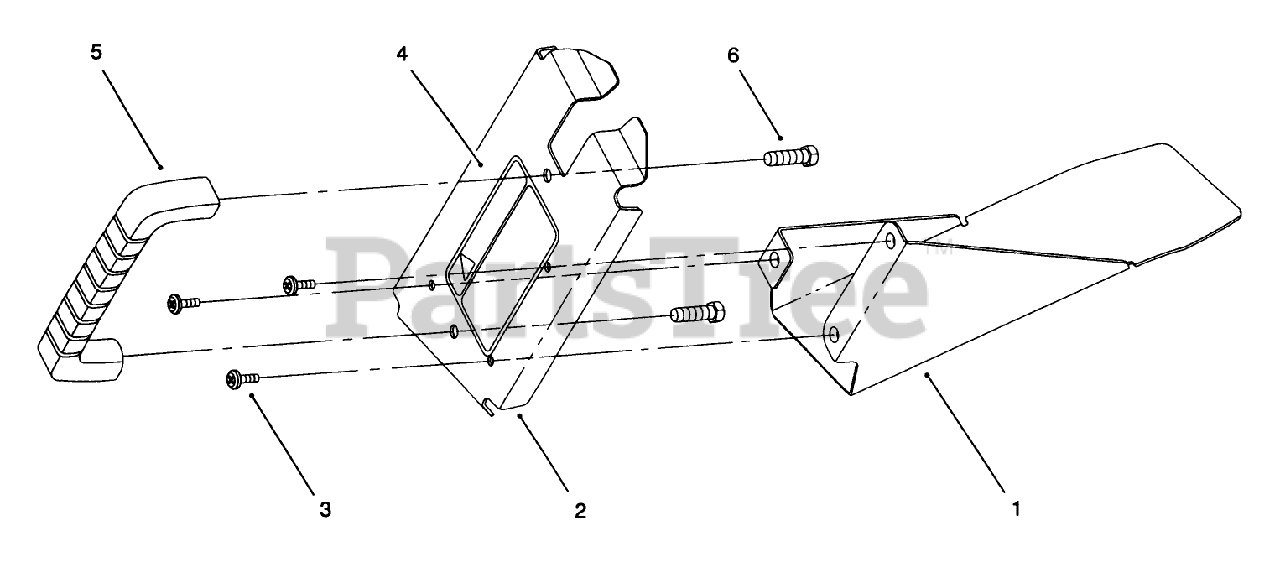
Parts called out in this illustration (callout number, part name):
4	DECAL - WARNING
5	HANDLE-DOOR
6	SCREW-HWH
